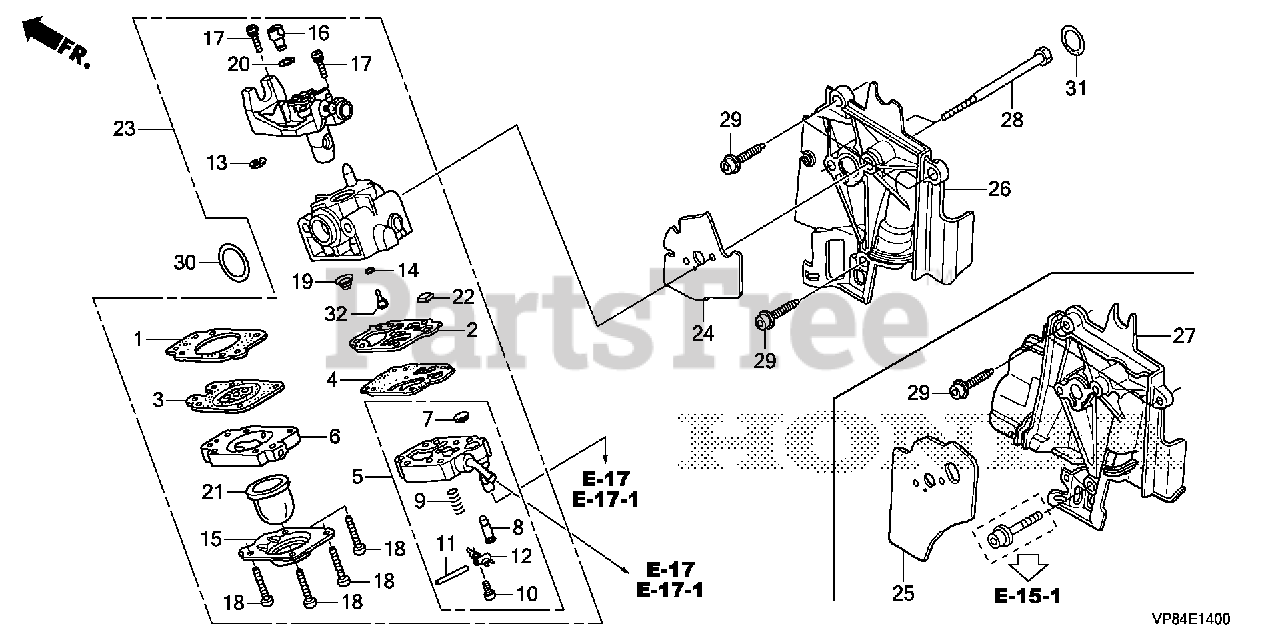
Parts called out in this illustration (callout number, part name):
1	GASKET, METERING DIAPHRAGM
2	GASKET, PUMP (CARBURETOR NO.)
3	DIAPHRAGM ASSY., METERING
4	DIAPHRAGM, PUMP
5	BODY ASSY., PUMP (CARBURETOR NO.)
6	BODY ASSY., AIR PURGE
7	SCREEN, INLET (CARBURETOR NO.)
8	VALVE, INLET NEEDLE
9	SPRING, METERING LEVER
10	SCREW, METERING LEVER PIN
11	PIN, METERING LEVER
12	LEVER, METERING
13	RING, RETAINING
15	COVER, PRIMER PUMP
17	SCREW, THROTTLE COLLAR
18	SCREW, PUMP COVER
19	SPRING, PUMP
21	PUMP, PRIMER
22	FILTER, FUEL INLET (CARBURETOR NO.)
23	CARBURETOR ASSY. (WYB 34A/B)
24	GASKET, CARBURETOR
26	SHROUD
28	BOLT (5X53)
29	BOLT, SOCKET (5X16)
30	O-RING (14.8X2.4)
31	O-RING (12.3X2.4) (CARBURETOR NO.)
32	JET (#33) (CARBURETOR NO.)
32	JET (#34) (CARBURETOR NO.)
32	JET (#32) (CARBURETOR NO.)
